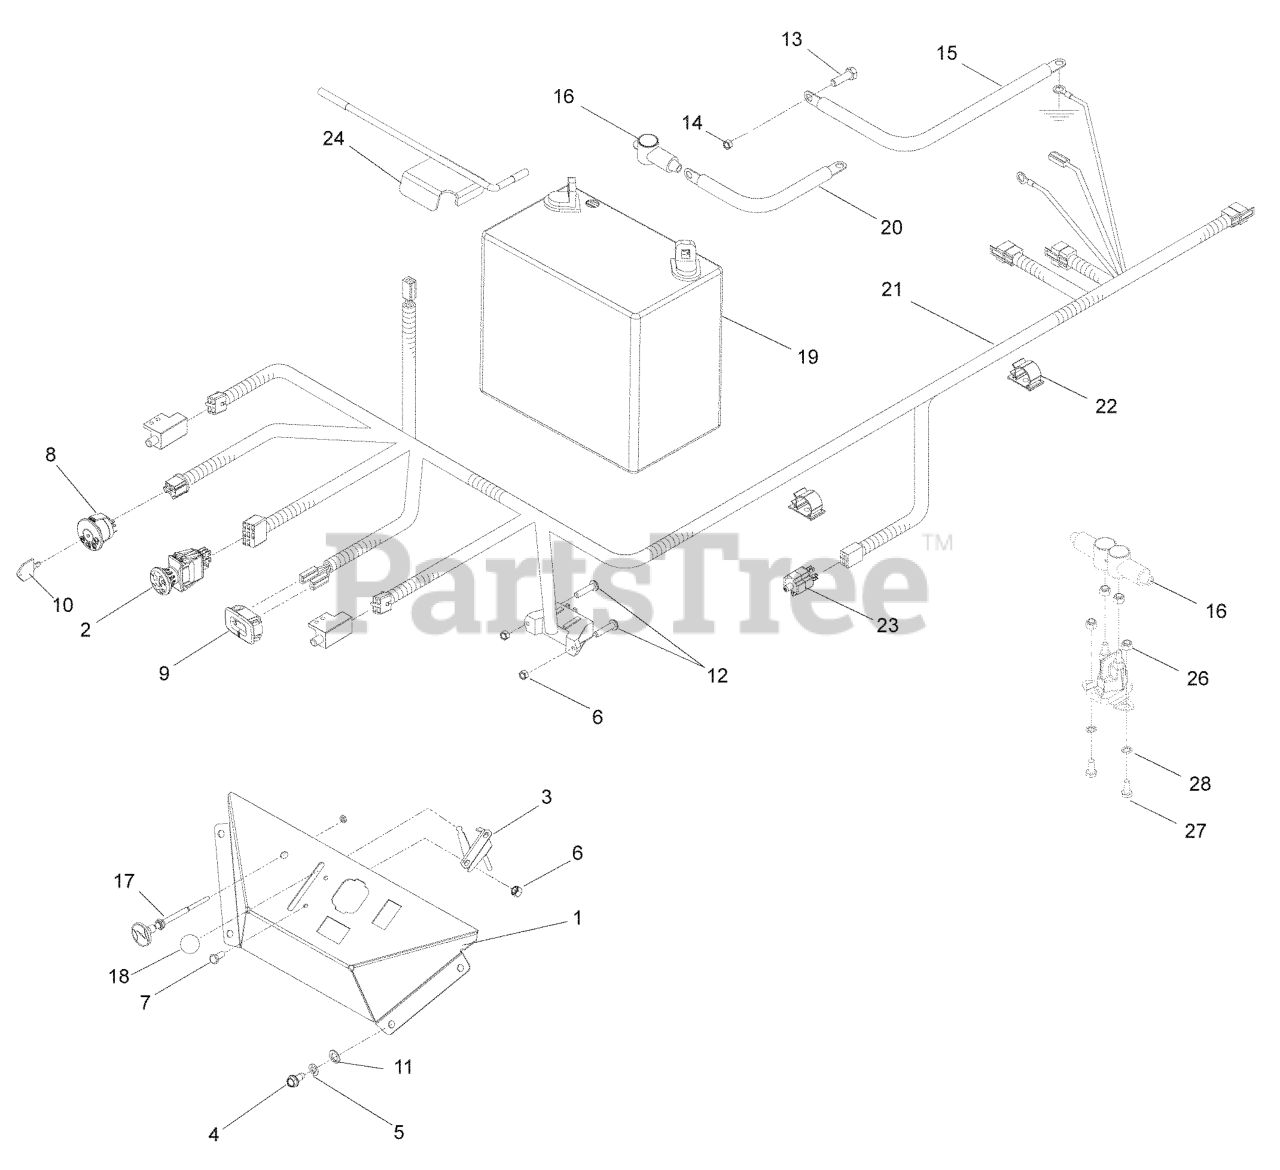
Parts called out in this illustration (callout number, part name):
1	CONSLE, ORANGE
2	SWITCH, PTO 10 AMP
3	THROTTLE CABLE
4	SCREW 1/4 X 5/8
5	LOCKWASHER 1/4"
6	NUT 10-24 NYLOC
7	HCS #10-24 X 1/2
8	RP IGNITION SWITCH
9	HOUR METER
10	KEY
11	WASHER 1/4 FLAT
12	SCREW, #1--24 X 1/2 SLOTTED
13	HCS 5/16C X 3/4
14	NUT 5/16 NYLOC
15	CABLE-NEGATIVE
17	CONTROL-CHOKE 57"
19	BATTERY, 12 V 330 AMP
20	CABLE POSITIVE, LONG
21	HARNESS, WIRING LZ/IZ
22	PUSH-MOUNT WIRE CLIP
23	SWITCH, BRAKE 3P
24	BATTERY HOLD DOWN
26	NUT.1/4-20.HEX.NYLOC.ZD
27	HCS 1/4C X 5/8
28	WASHER 1/4 INT TOOTH
